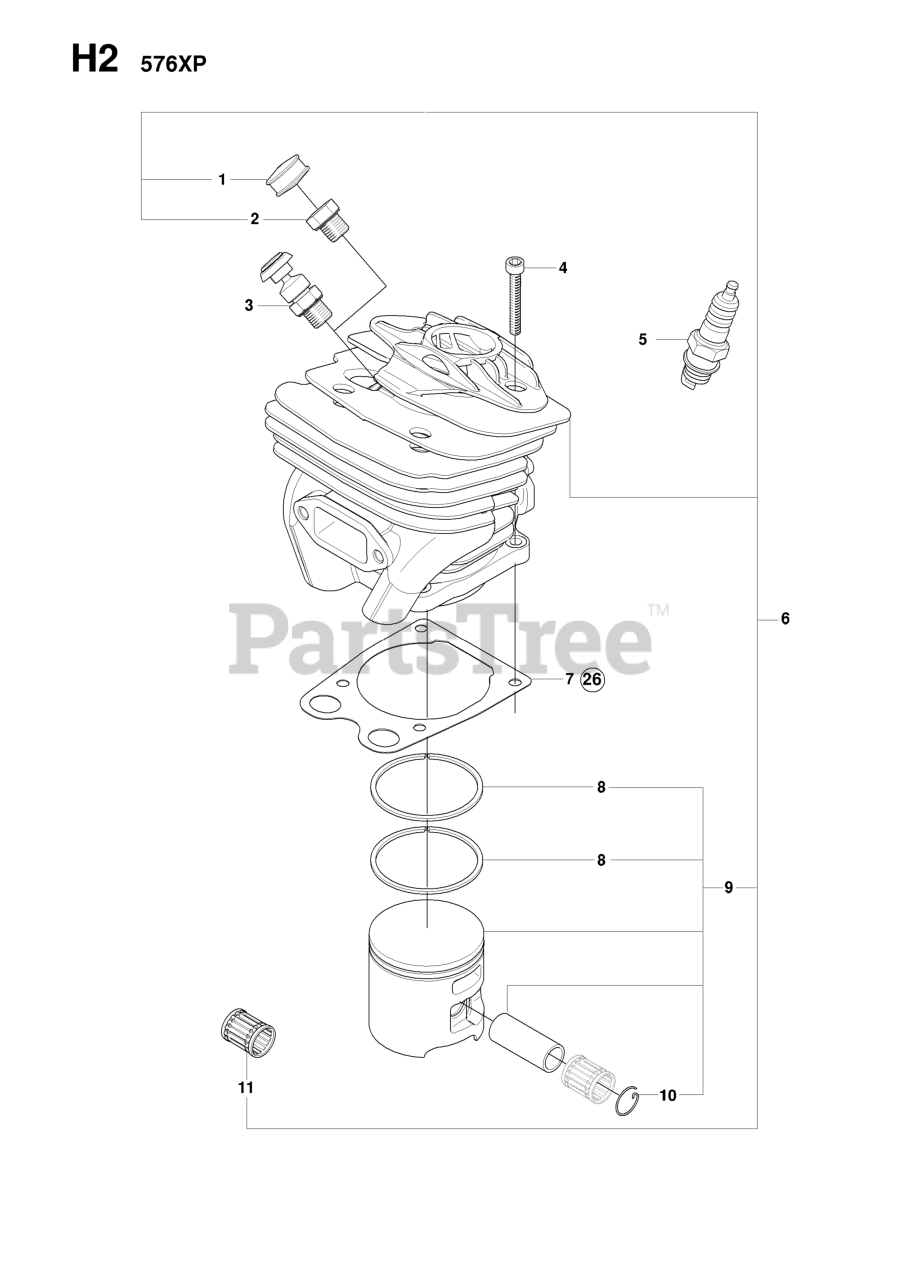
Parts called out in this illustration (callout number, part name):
2	CYLINDER PLUG
3	VALVE
4	SCREW MC6S 5X25
5	SPARK PLUG M14X1.25 NGK BPMR7A
6	CYLINDER ASSY
8	%PISTON RING
9	PISTON
10	WRIST PIN CLIP
11	SUPPORT BUSHING
26	GASKET KIT
